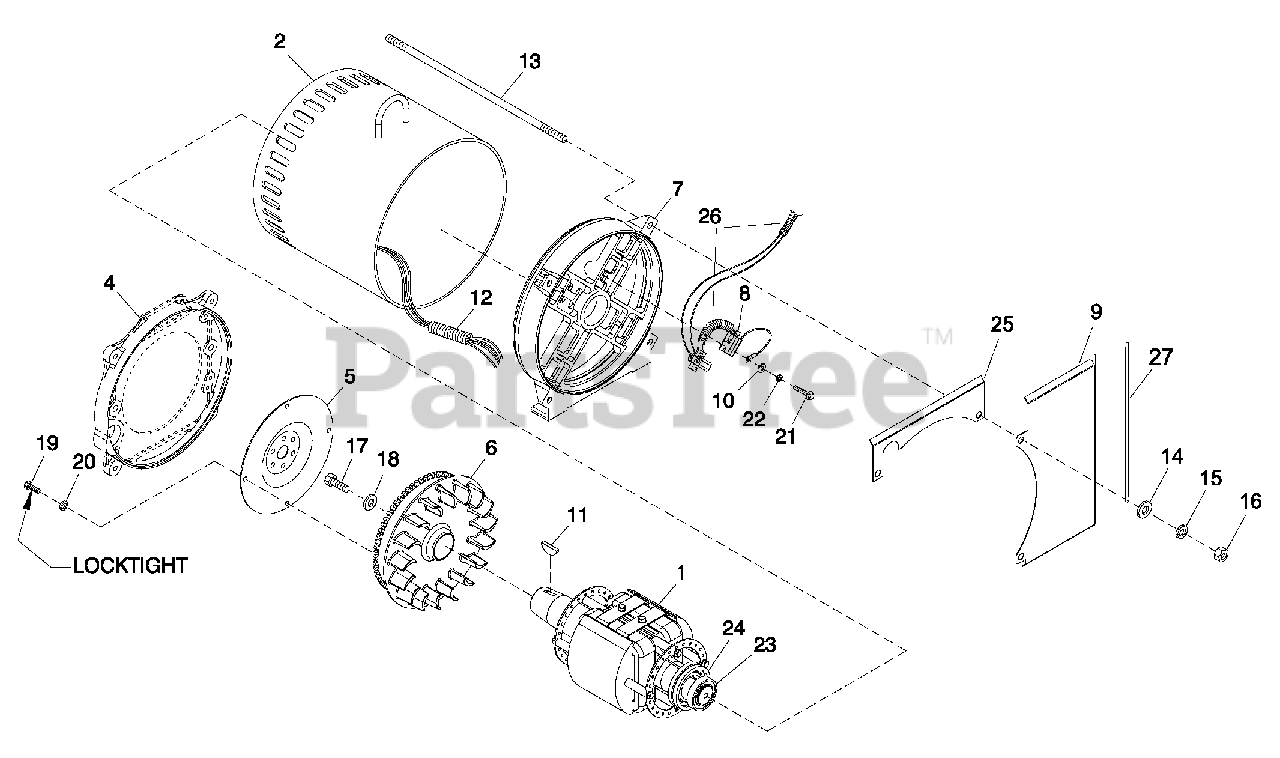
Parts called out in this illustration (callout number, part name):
1	R0T0R-2390-45KD1 CPL
2	STAT0R-390 45K 2P 1PH DIRECT
3	INSTR HYP0T TEST (N0T SH0WN)
4	ENGINE ADAPTER
5	FLEXPLATE
6	ASSY FLYWHEEL CPL W/40MM FAN B
7	REAR BEARING CARRIER 390/DRCT
8	ASSY BRUSH H0LDER 390/HSB
9	GUARD REAR BEARING CARRIER
10	WASHER FLAT #8 ZINC
11	KEY W 00DRUFF #E
12	C0NDUIT FLEX 1.0" ID (35" LG)
13	STUD M 14-2.0 570 G5 ZINC
14	WASHER FLAT M14
15	WASHER L0CKM14
16	NUT HEXM14-2.0G8YEL CHR
17	SCREW HHCM16-2.0X 45 G8.8
18	SPACER .69 X 2.75 X .37 ST/ZNC
19	SCREW HHC M10-1.50 X 16 G10.9
20	WASHER L0CKM10
21	SCREW HHTT M4-0.7 X 16 BP
22	WASHER L0CK#8-M4
23	BALL BEARING-45 MM
24	SLIP RING MACHINED
25	GUARD REAR BEARING CARRIER
26	C0NDUIT FLEX .38" ID (60")
27	TRIM VINYL BLACK 1/8GP (16.5"LG)
